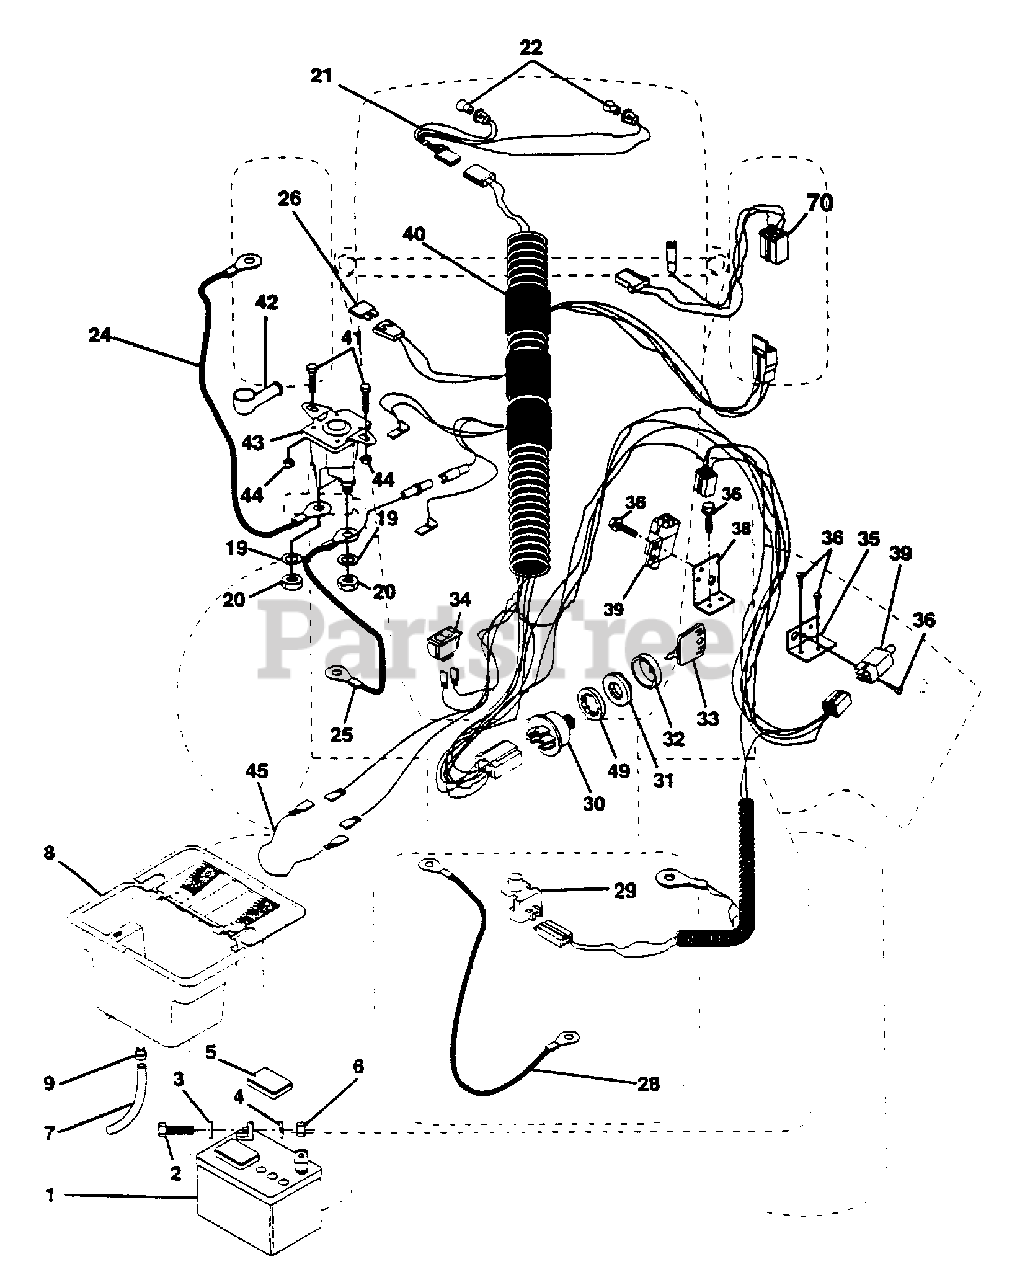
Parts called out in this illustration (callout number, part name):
2	BOLT LT
3	WASHER
4	LOCKWASHER
5	"CAP,BATTERY "
7	TUBE T
9	HOSE CLAMP T
20	NUT
21	"HARNESS,LIGHT SOC"
22	HEADLAMP BULB
24	"CABLE T, BATTERY"
25	CABLE.BTRY.6GA.RD
26	FUSE HYT
28	CABLE T
29	SWITCH SEAT
32	COVER KEY SWITCH
33	KEY MLD GEN DELTA
34	SWITCH LT
35	BRACKET LT
36	SCREW
38	BRACKET SWITCH IN
39	SWITCH INTERLOCKT
40	HARNESS.IGN.DASH.
41	BOLT.HX.1/4-20
44	NUT
45	ADAPTER AMMETER
49	LOCKWASHER
70	HARNESS ENG DUAL
